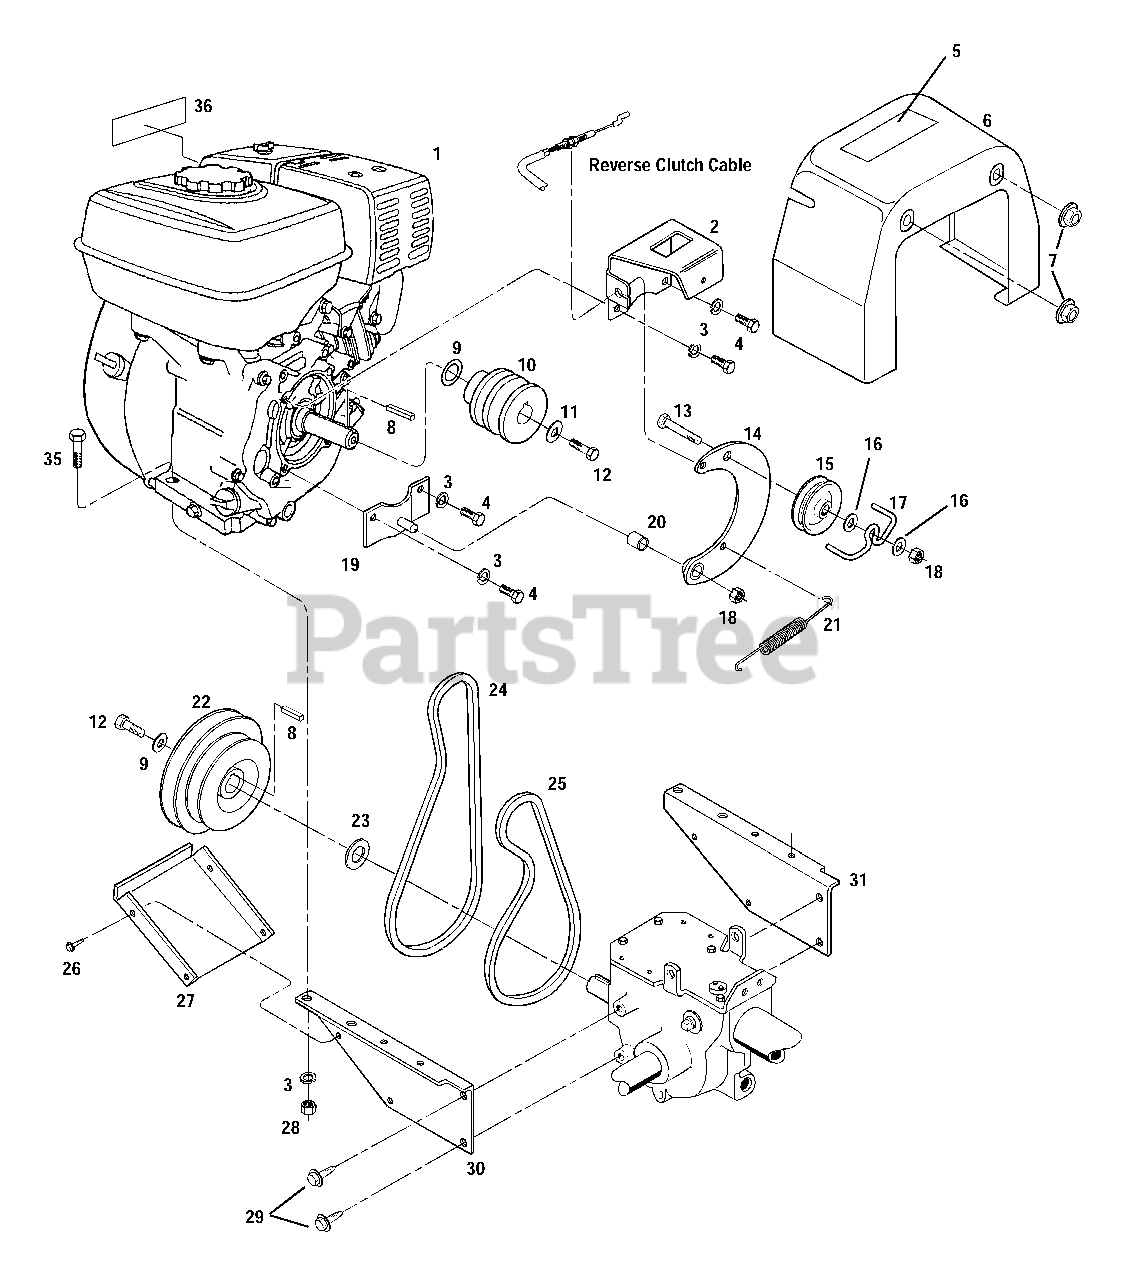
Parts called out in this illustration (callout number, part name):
1	Engine-5.5 HP, standard recoil start
2	Bracket, Clutch Cable
3	Lockwasher-5/16
4	Screw-hex hd., 5/16-24 x 1/2
5	Decal-Hot surfaces/belt warning
6	Cover-
7	Nut-5/16-18, Flange Lock
8	Key-3/16 x 1-1/2
9	Washer-Disc Spring
10	Pulley, Engine Drive
11	Washer, Belleville
12	Screw-hex hd., 5/16-24 x 1-1/8
13	Screw-hex hd., 5/16-18 x 2
14	Reverse Idler Arm
15	Pulley, Reverse Idler
16	Washer, Flat, 5/16
17	Belt Guide
18	Locknut, 5/16-18
19	Bracket, Reverse Idler
20	Bushing
21	Spring, Reverse Return
22	Pulley, Transmission
23	Support Washer
24	Reverse Drive Belt
25	Forward Drive Belt
26	Screw-hex hd., #10-32 x 1/2, self-tapping
27	Guard, Belts/Pullyes
28	Hex Nut, 5/16-18
29	Screw-flanged hex hd., 5/16-18 x 3/4
30	Support Bracket-engine, left side
31	Support Bracket-engine, right side
35	Screw-hex hd., 5/16-18 x 1-1/2
36	Decal-Stabilization
